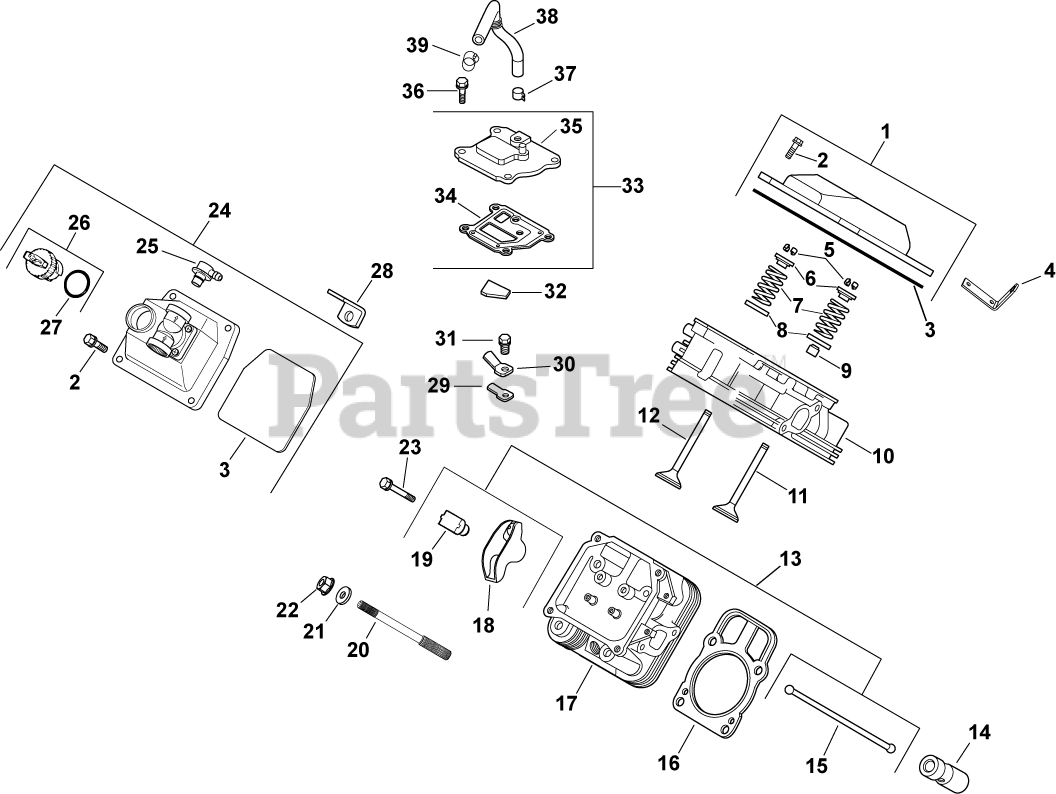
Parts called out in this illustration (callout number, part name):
1	KIT, VALVE COVER-PLAIN
2	SCREW, FLG M6X1.0X30
3	O-RING (YELLOW) -USE 24 153 30-S
4	STRAP, LIFTING-USE 25 445 03-S
5	KIT, RETAINER
6	RETAINER, VALVE SPRING - USE 25 173 28-S
7	SPRING, VALVE
8	RETAINER, SPRING
9	SEAL, VALVE STEM - (#2503214S)
10	HEAD, SERVICE ASSY CYL #1-USE 24 318 106
11	VALVE, INTAKE (STD)
12	VALVE, EXHAUST (STD) - USE 32 016 01-S
13	KIT, VALVE TRAIN
14	LIFTER, HYDRAULIC VALVE-USE 25 351 10-S
15	ROD, PUSH
16	CYL HEAD GASKET KIT-USE 24 841 04-S
17	HEAD, SERVICE ASSY CYL #2-USE 24 318 114
18	ARM, ROCKER
19	PIVOT, CYLINDRICAL ROCKER ARM-USE 24 599
20	STUD, M8X1.25
21	WASHER, FLAT 8.6 MM
22	NUT, FLG M8X1.25
23	SCREW, ROCKER ARM PIVOT-USE M-640034-S
24	KIT, VALVE COVER-FUEL PUMP
25	CONNECTOR 90 DEGREE use 25 294 11-S
26	CAP ASSY, OIL FILL (YELLOW)
27	O-RING-USE 24 153 32-S
29	REED, BREATHER
30	RETAINER, REED
31	SCREW, FLG THD FRM M5X.8X10
32	FILTER, BREATHER-USE 24 050 11-S
33	KIT, BREATHER ASSEMBLY
35	COVER, BREATHER -USE 24 033 01-S
36	SCREW,FLG THD FRM M6X1.0X20-(#25086396S)
37	CLAMP, BAND SPRING HOSE-(#2523737S)
38	HOSE, BREATHER-USE 24 326 96-S
39	CLAMP, HOSE (KM)-USE 25 237 31-S
2401602-S	VALVE, EXHAUST (.25)
2401702-S	VALVE, INTAKE (.25)
